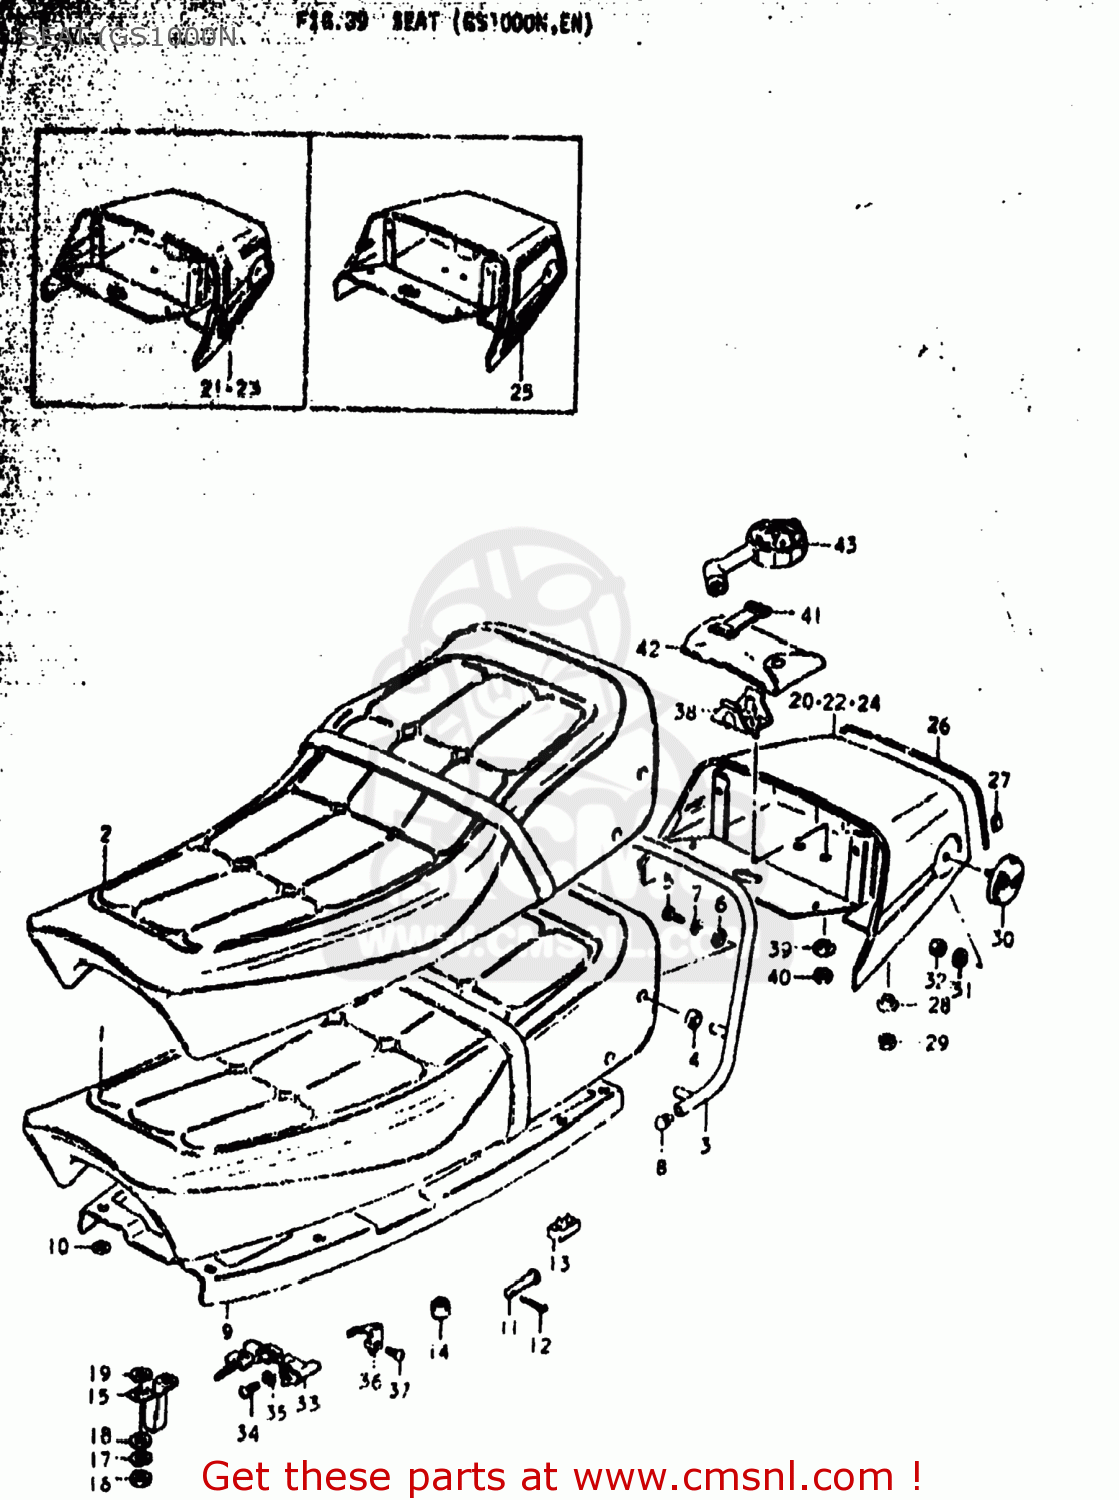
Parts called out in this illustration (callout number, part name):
1	SEAT ASSEMBLY
2	SEAT ASSEMBLY
3	HANDLE,PILLION RIDER
4	CUSHION
5	BOLT
6	WASHER
7	LOCK WASHER
8	END,SHEET HANDLE
9	MOLDING,SEAT
10	NUT
11	PIN
12	PIN
13	CUSHION
14	CUSHION
15	STRIKER,SEAT LOCK
16	NUT
17	LOCK WASHER
18	WASHER
19	WASHER (6.5X20X1.2)
20	COVER,SEAT TAIL
21	TAPE SET
22	COVER,SEAT TAIL
23	TAPE SET
24	COVER,SEAT TAIL
25	TAPE SET
26	GROMMET
27	CLIP,SEAT TAIL COVER M
28	WASHER
29	NUT 6MM
30	REFLEX REFLECTOR,RR
31	WASHER
32	NUT
33	LOCK ASSY,SEAT
34	SCREW
35	LOCK WASHER
36	SPRING,HELMET HOLDER
37	SCREW
38	HOLDER,TOOL
39	WASHER
40	NUT
41	BAND
42	TOOL SET
43	GAUGE ASSEMBLY,AIR PRESSURE
